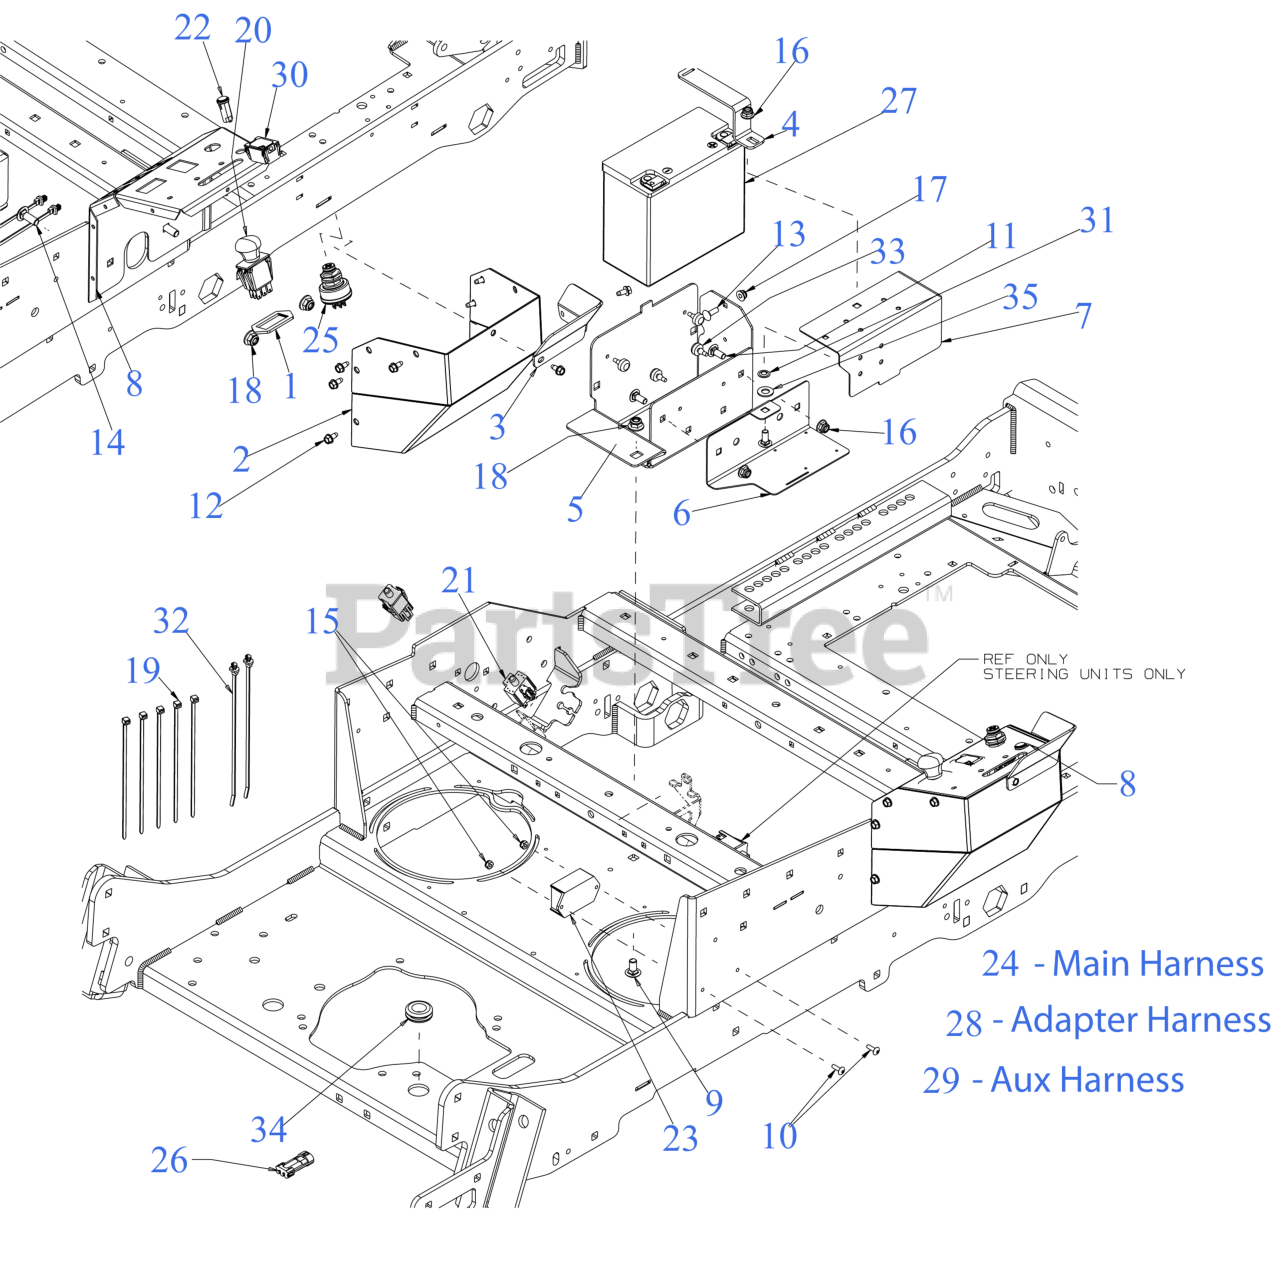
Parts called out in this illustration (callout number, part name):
1	BRACKET-PTO SWITCH
4	BATTERY SUPPORT BRACKET
5	BATTERY MOUNT BRACKET
6	MOUNT BRACKET (LOWER)
7	COVER BRACKET (UPPER)
8	CONTROL POD (RH)
9	CARRIAGE BOLT 3/8-16 x .750 GR5
10	SCREW #10-24 x .62
11	CARRIAGE BOLT 5/16-18 x .75
12	SCREW 1/4-20 X.500
13	SCREW 1/4-20 x .75 GR5
14	CARRIAGE BOLT 3/8-16 x 1.00 GR5
16	FLANGE LOCK NUT 5/16-18
17	FLANGE LOCK NUT
19	7" CABLE TIE
20	PTO SWITCH (BLACK KNOB) TEXT SYM
21	3 POLE SWITCH ( NC-NO-NO)
22	INDICATOR LIGHT-RED
23	CONTROL PANEL (SOFT CLUTCH)
24	WIRE HARNESS ASSEMBLY (KOH/KAW EFI)
25	KEY SWITCH (3 POSITION)
25	PRO-Z KEY SET
26	SEALED CAP ASSEMBLY
27	BATTERY (300 CCA)
28	HARNESS ADAPTER (KAW EFI)
29	AUX POWER HARNESS
30	HOUR METER
32	CABLE TIE
33	BUMPER, .62 DIA x .3
34	RUBBER GROMMET
35	FLAT WASHER
